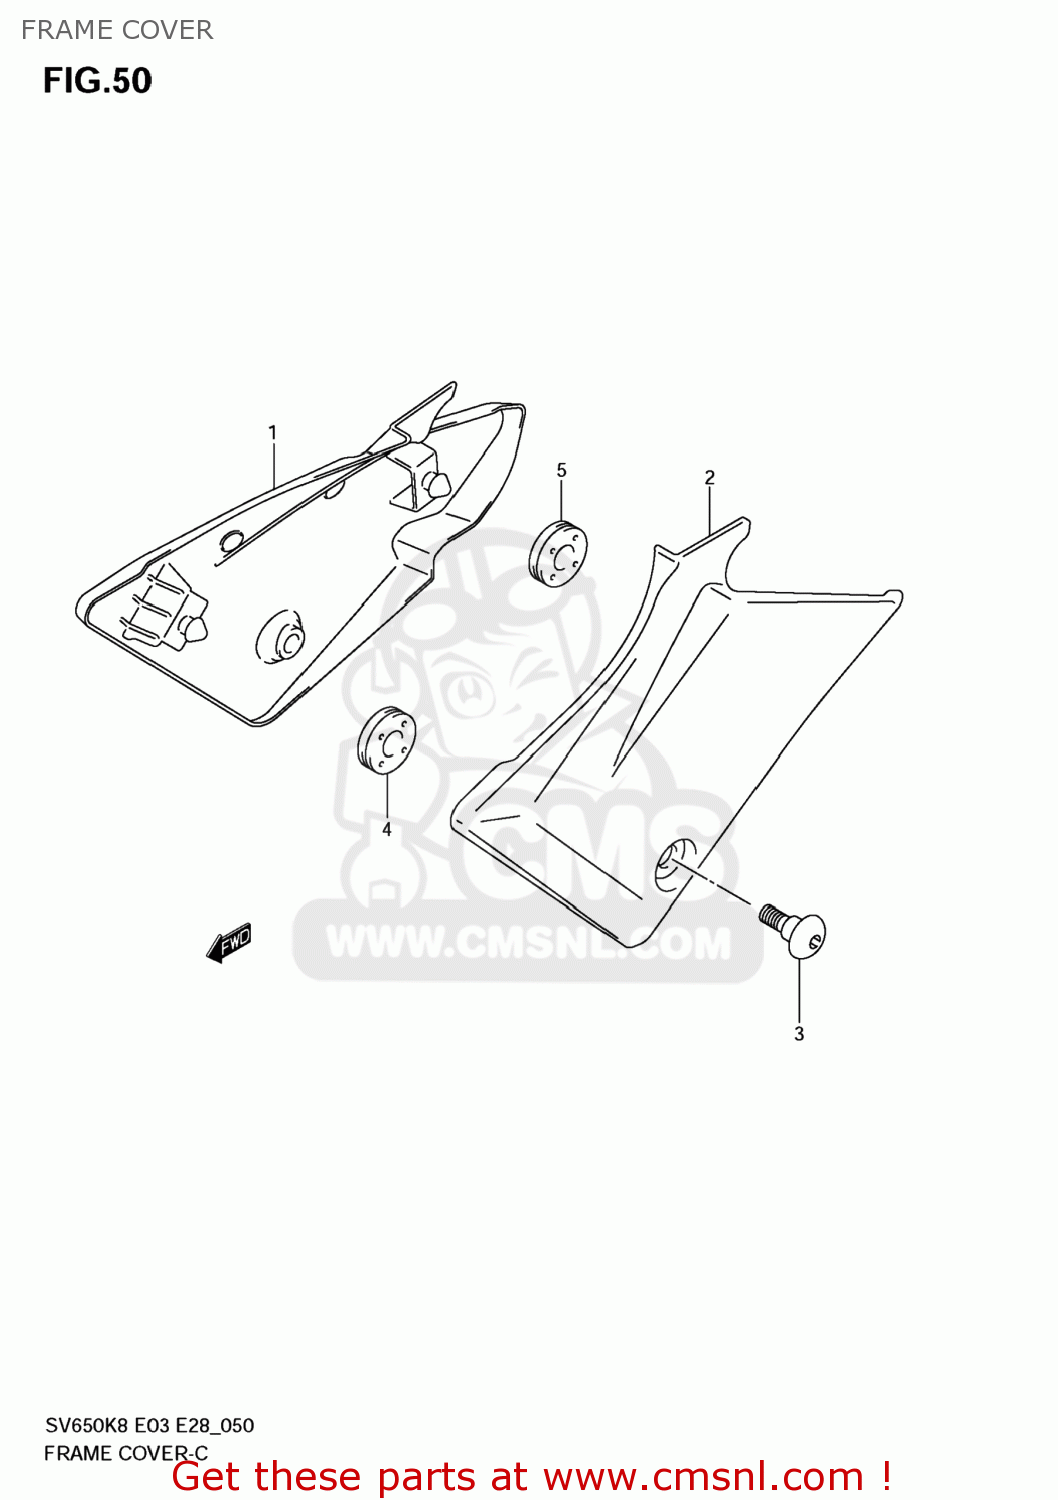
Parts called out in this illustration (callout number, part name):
1	COVER,FRAME,R(BLACK)
2	COVER,FRAME,L(BLACK)
3	SCREW(6X16)
4	CUSHION
5	CUSHION
